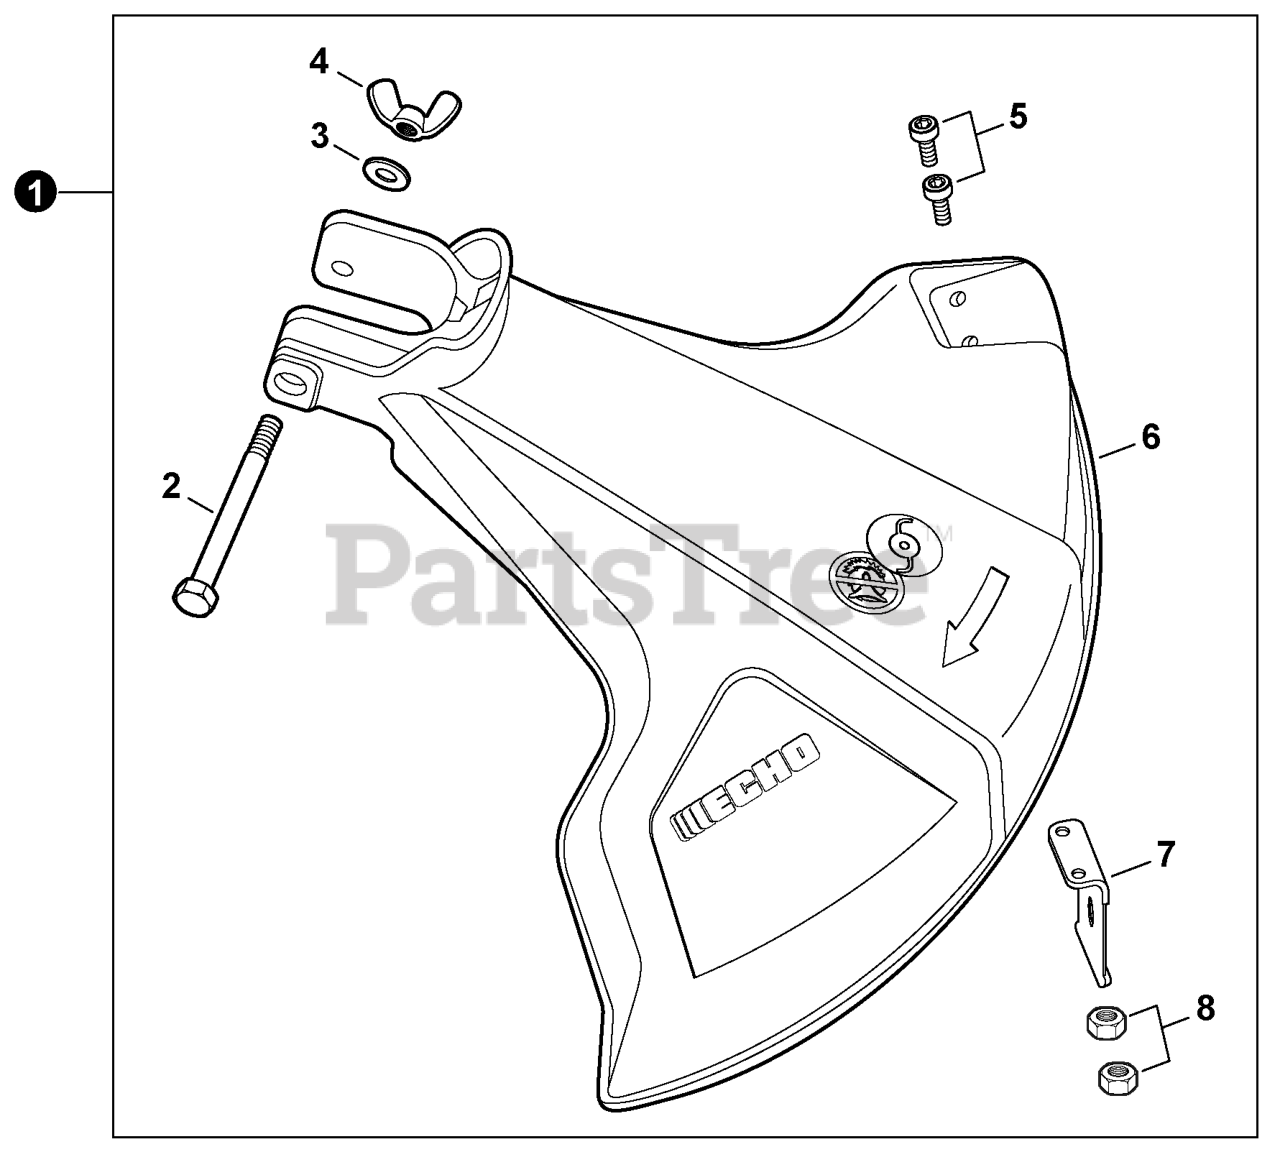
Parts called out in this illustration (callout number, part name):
1	SHIELD ASSY, DEBRIS
2	BOLT 1/4"-20x2"
3	WASHER, 1/4"
4	NUT, WING 1/4"-20
5	BOLT, TORX 5x12
6	SHIELD, DEBRIS
7	CUTTER, LINE
